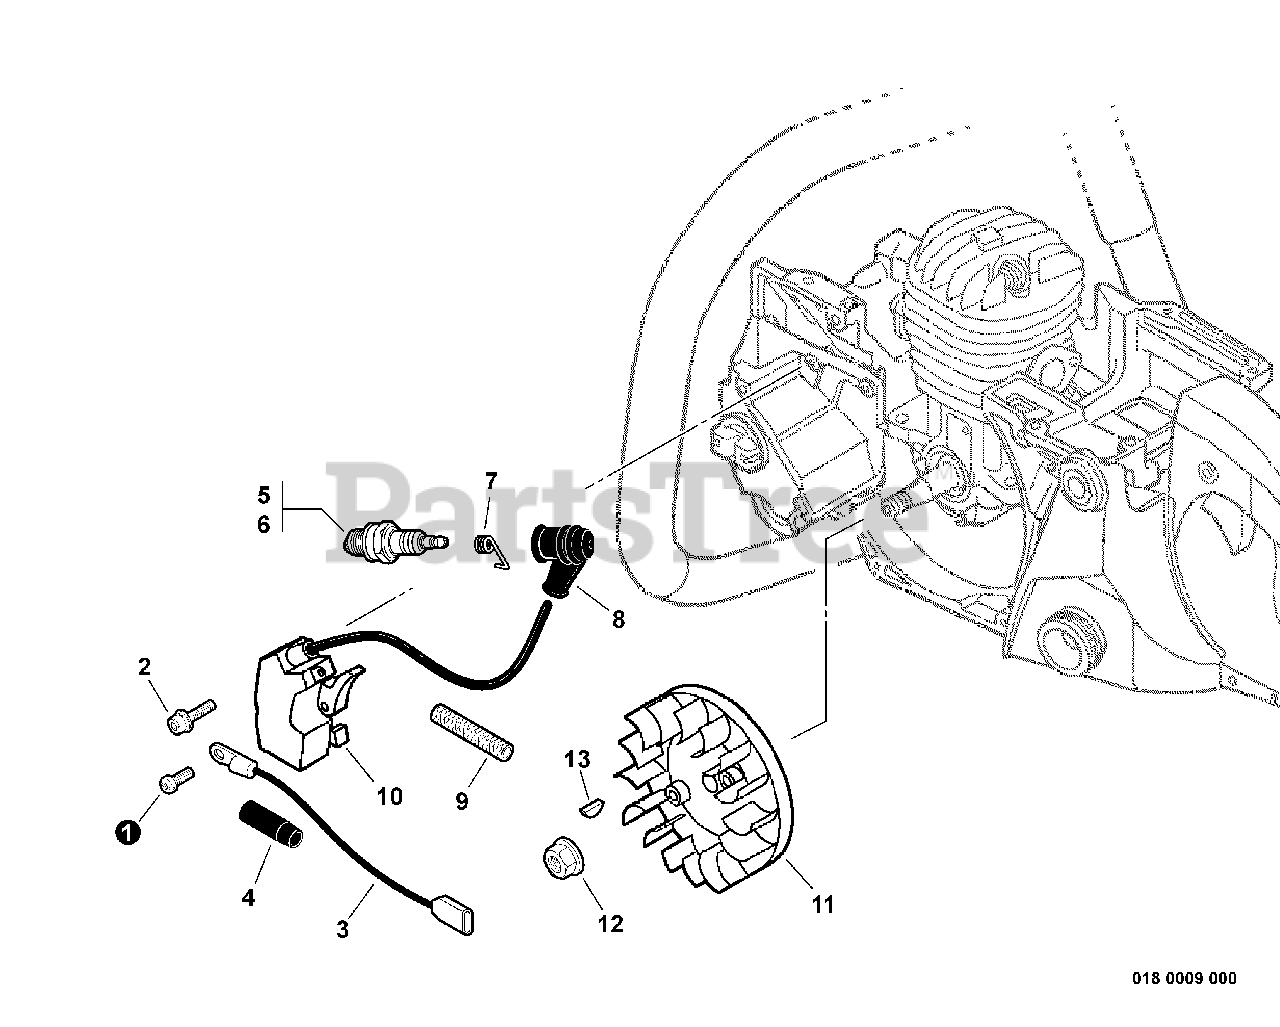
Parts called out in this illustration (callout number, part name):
1	SCREW 4×6
2	BOLT 4×30
3	LEAD #250-210-LA104
4	BOOT, CONNECTOR
5	SPARK PLUG - BPM8Y
6	SPARK PLUG - BPMR8Y
7	TERMINAL, SPARK PLUG
8	CAP, SPARK PLUG
9	TUBE, INSULATOR 7×8.6×40
10	COIL, IGNITION
11	FLYWHEEL
12	NUT, FLANGE M8
13	KEY, WOODRUFF
